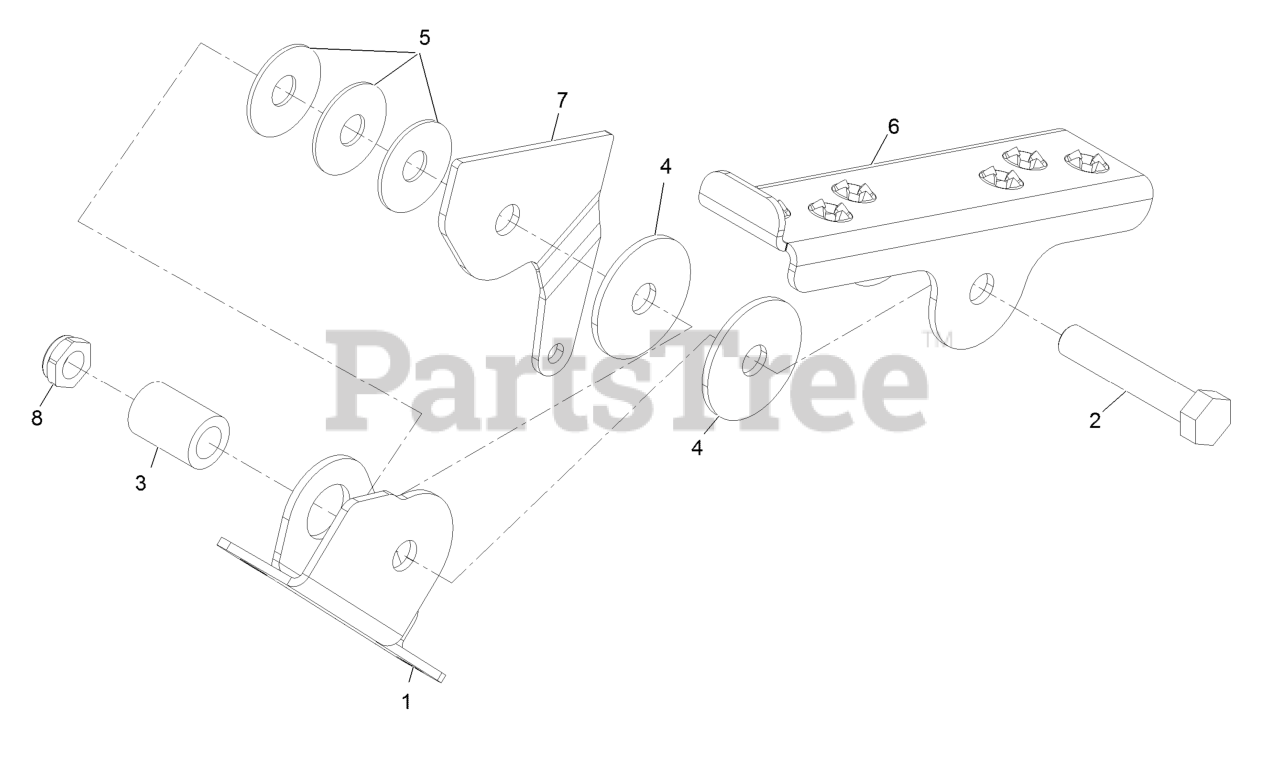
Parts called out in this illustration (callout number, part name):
1	BRACKET-PEDAL MOUNT
2	SCREW-HH
3	SPACER-ROLLER
4	DISC-FRICTION
5	WASHER-DISC, SPRING
6	CHANNEL,PEDAL LINK
7	ARM, FOOT PEDAL
8	NUT-HEX
